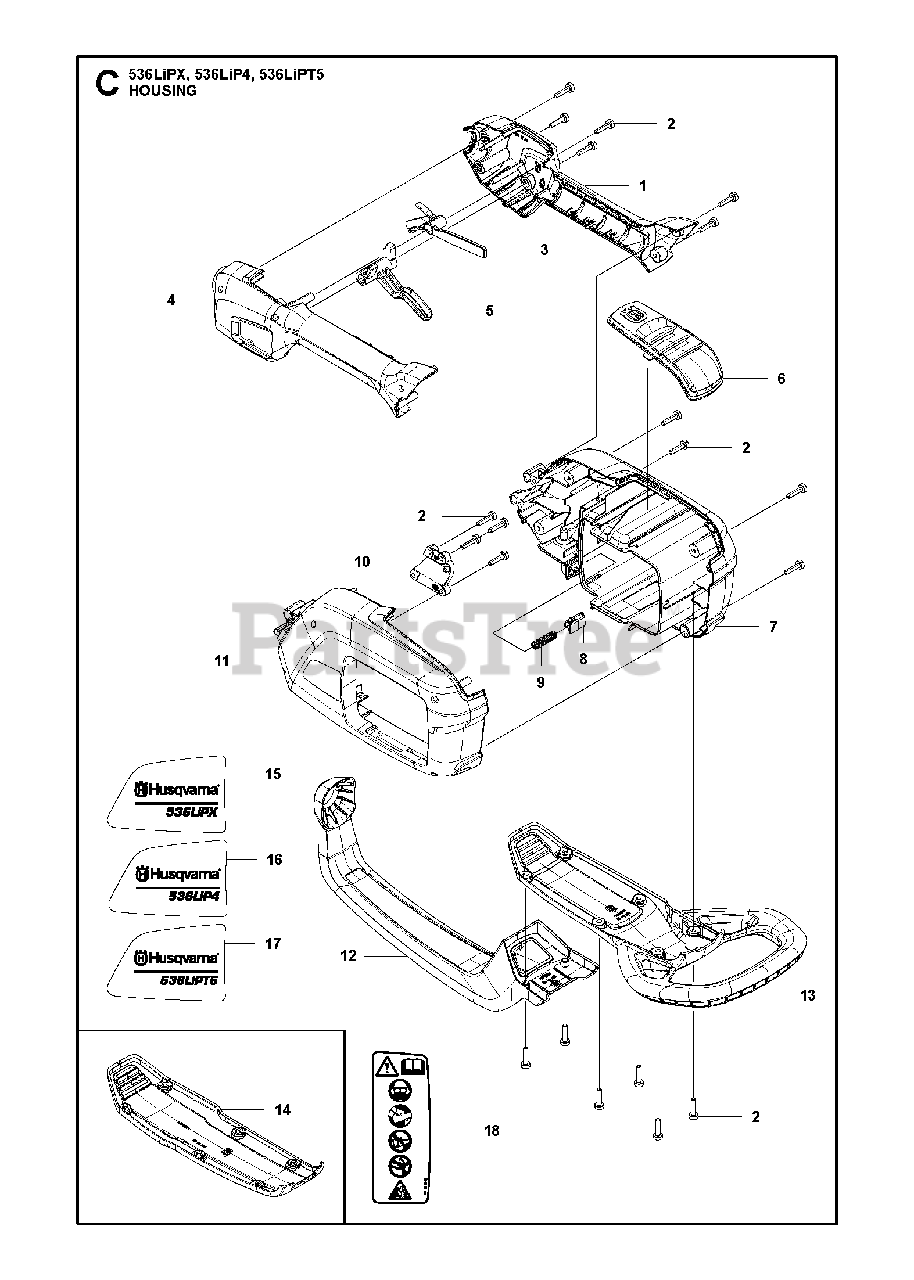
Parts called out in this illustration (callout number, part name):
1	Right Half Handle
2	SCREW
3	THROTTLE LOCKOUT
4	HANDLE HALF LEFT
5	TRIGGER
7	Housing, RH
8	PUSH BUTTON
9	SPRING PUSH OUT
11	HOUSING LEFT
12	TRIGGER GUARD
13	BUMPER SKID PLATE
14	SKID PLATE
15	DECAL PRODUCT LIPX
16	DECAL PRODUCT LIP4
17	DECAL PRODUCT LIPT5
